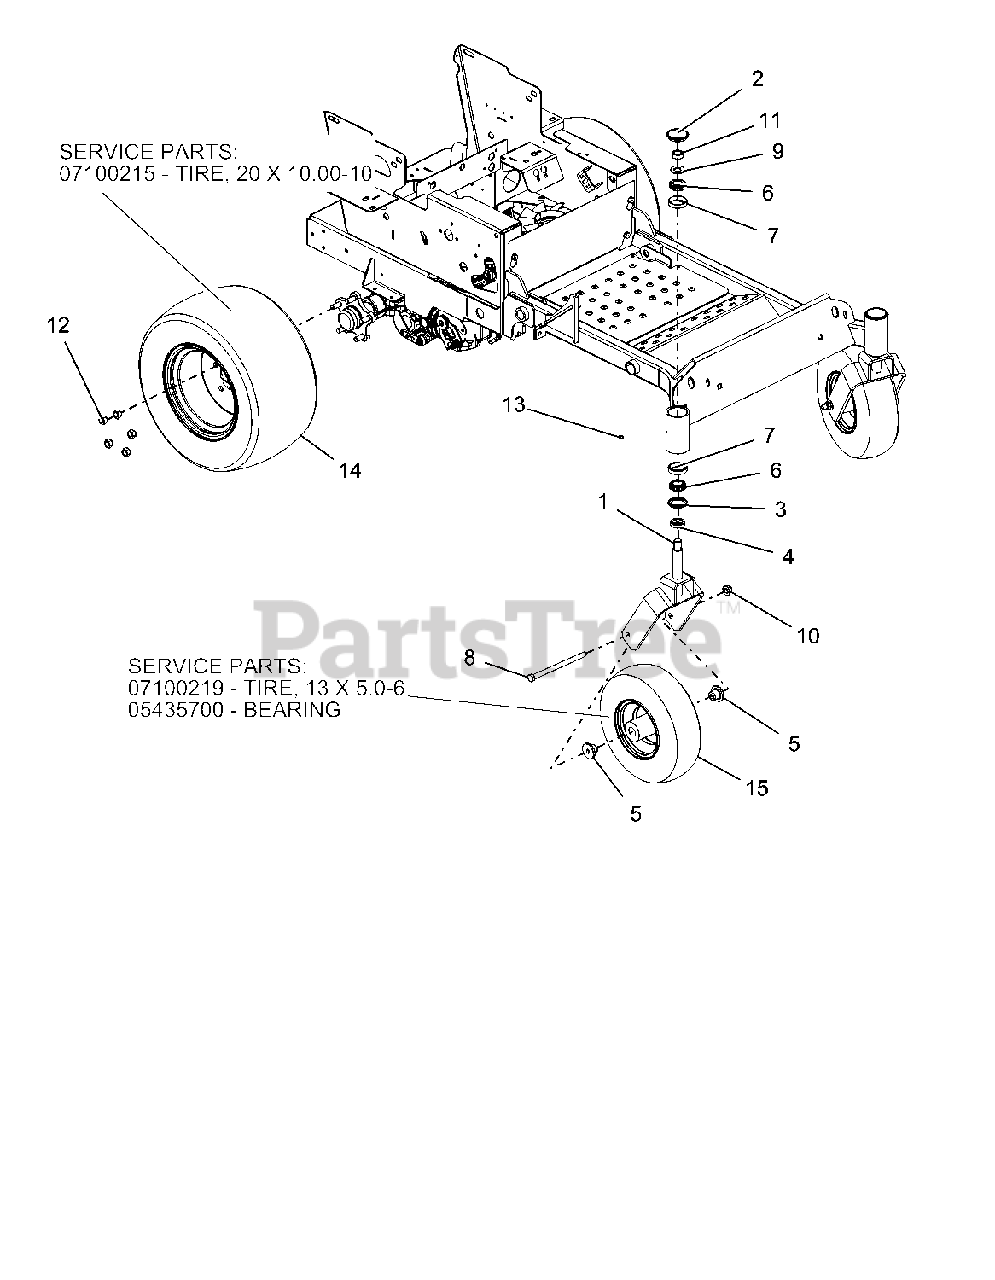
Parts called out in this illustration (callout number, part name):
1	WLDMT, CASTER FORK
2	CAP, DUST
3	BEARING SEAL 1.5 X 2.0 X .18
4	SPCR, 1.005X1.5075X.375
5	SPACER, FRONT WHEEL
6	BRG, CONE 1.000 X .580
7	BRG, CUP 1.980 X .420
8	BLT-HEX .50-13X7.50 GR5 YWZC
9	WSHR-FL-STL.812X1.50X.135YWZC
10	NUT-LK-NYL-FLG .50-13 YWZC
11	NUT-LK-TOP-JAM .75-16 YWZC
12	NUT, LUG .500-13
13	FITTING, .250-28 FLUSH MOUNT GREASE
14	TIRE/WHEEL, ASSY, 20X10.00-10
14	TIRE, 20 X 10.00-10
15	TIRE/WHEEL, ASM , 13X5-6
15	TIRE, 13 X 5.0-6
15	BEARING
